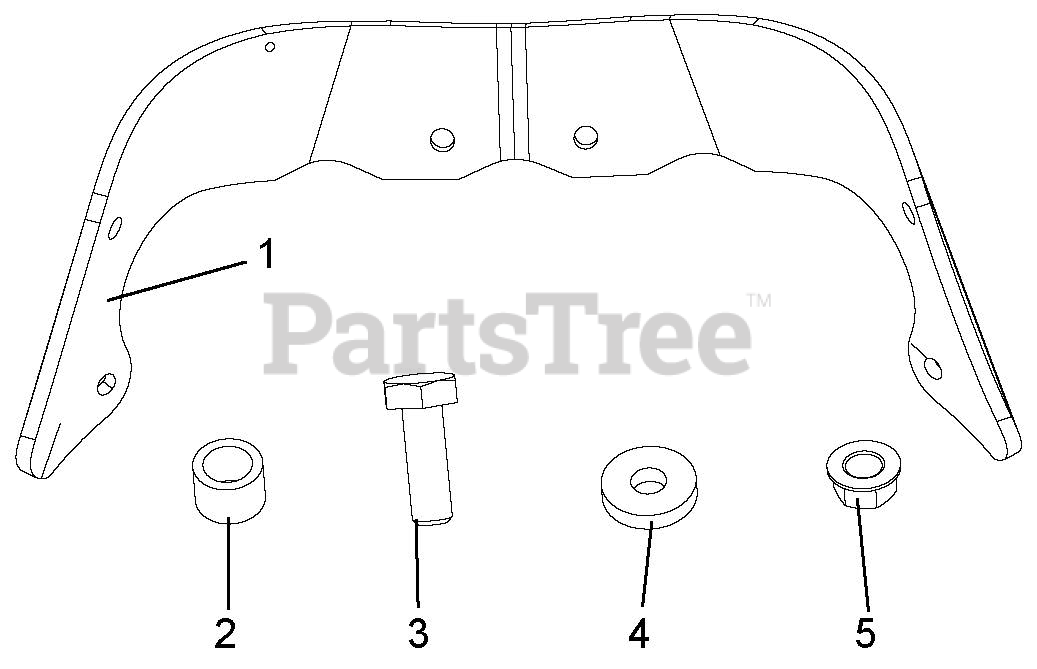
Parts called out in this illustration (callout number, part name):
1	FLIGHTING, AUGER (HIGH WEAR)
2	BUSHING,.26 ID X .44 OD X .375
3	@BLT-HEX .25-20X1.00 GR5 YWZC
4	@WSHR-FL-STL.312X.734X.065 YWZ
5	@NUT-LK-TOP-FLG .25-20 YWZC
